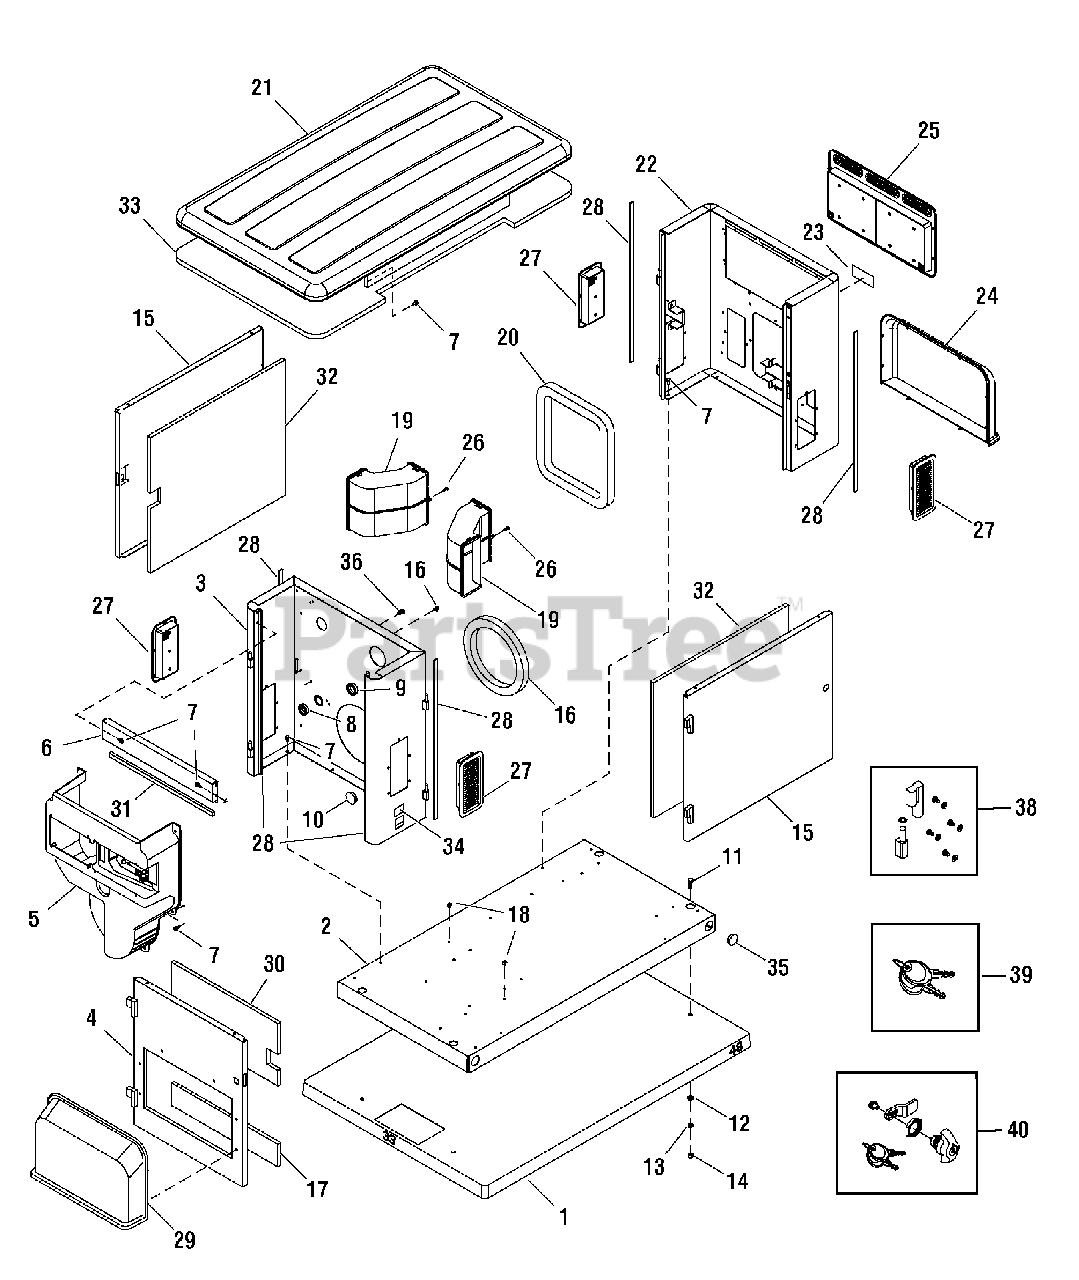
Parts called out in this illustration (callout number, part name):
3	BULKHEAD ASSEMBLY, Engine
4	DOOR ASSEMBLY, Engine
5	DUCT ASSEMBLY, Engine Air
6	SUPPORT RAIL ASSEMBLY
7	SCREW, Hex Head, Trilobular, 1/4-20 x 1/2
8	BUSHING, Snap, 1-3/8"
9	BUSHING, Snap, 1-1/2"
10	PLUG, Dome, 1-1/2"
11	* CAPSCREW, Hex Head, 3/8 - 16 x 1
12	* WASHER, Flat, 3/8 - M10
13	* WASHER, Lock 3/8
14	* NUT, 3/8-16
17	INSULATION, Engine Door, Bottom
18	MOUNT, Tie Wrap
20	SEAL, Foam, Alt Inlet
22	BULKHEAD ASSEMBLY, Alternator
23	DECAL, Caution Hot Muffler
24	COVER, Air Intake Alternator
25	VENT ASSEMBLY, Exhaust
27	VENT ASSEMBLY, Alternator
29	COVER, Air Intake Engine
30	INSULATION, Engine Door, Top
32	INSULATION, Front/Rear Door
33	INSULATION, Roof
34	DECAL
